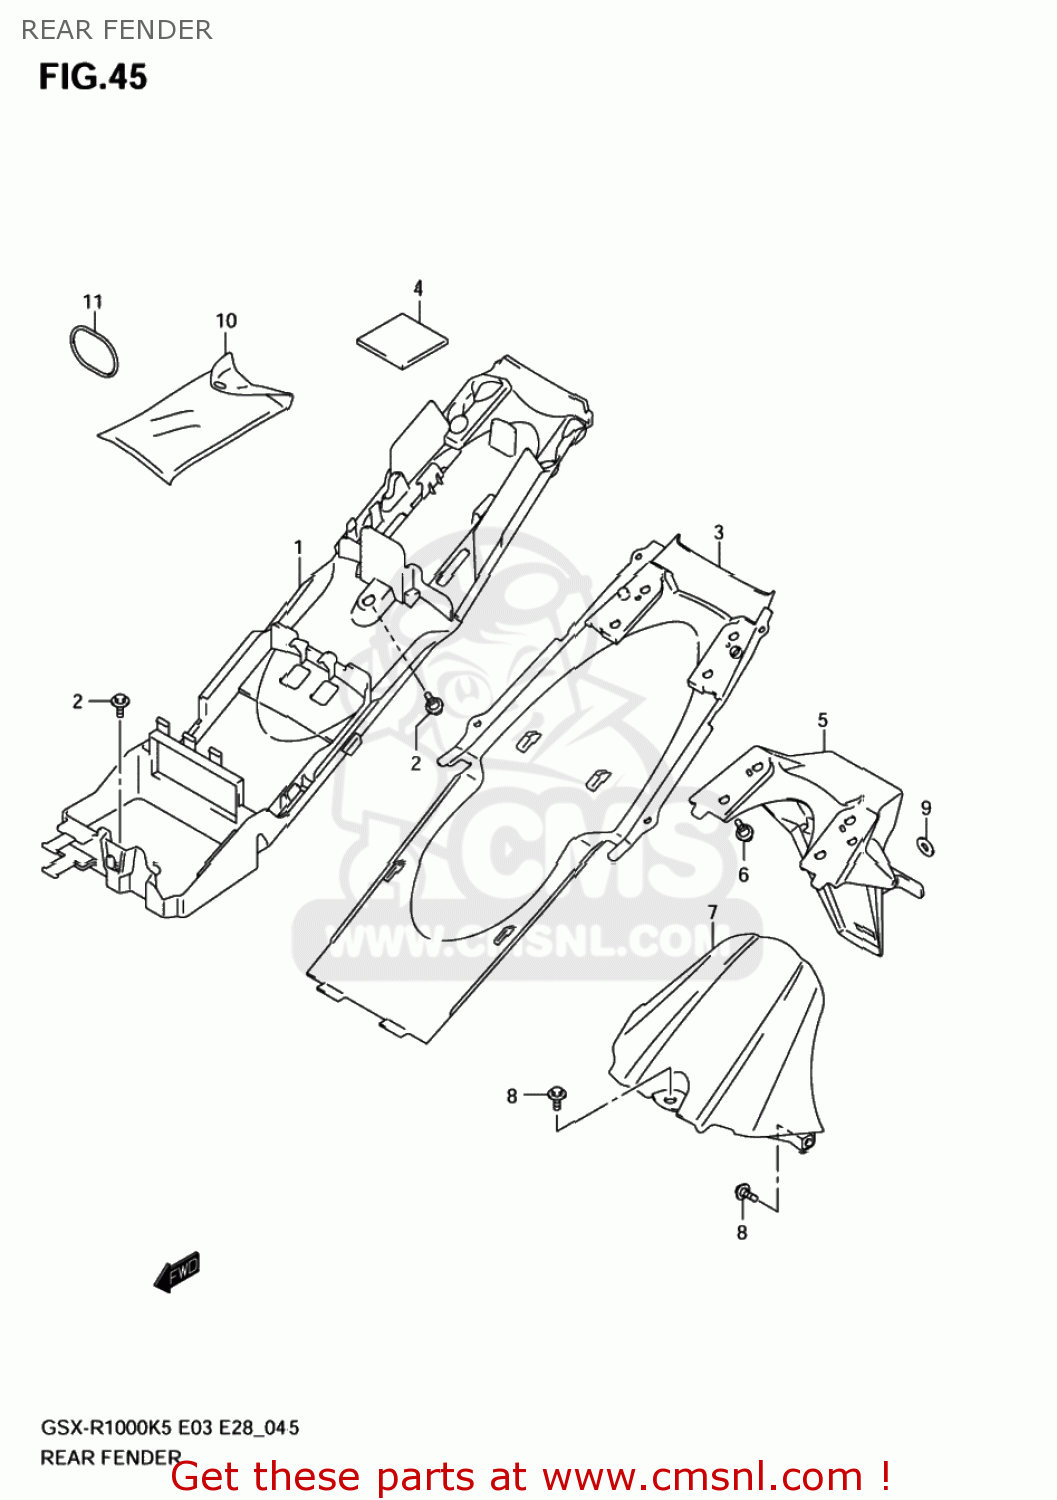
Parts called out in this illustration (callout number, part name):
1	FENDER,RR FR
2	BOLT
3	COVER,RR FENDER FR
4	CUSHION,UNDER COWLING
5	FENDER,RR RR
6	BOLT(6X16)
7	FENDER,RR LWR
8	BOLT
9	WASHER
10	TOOL ASSY
11	O RING(D:3.5,ID:61)
